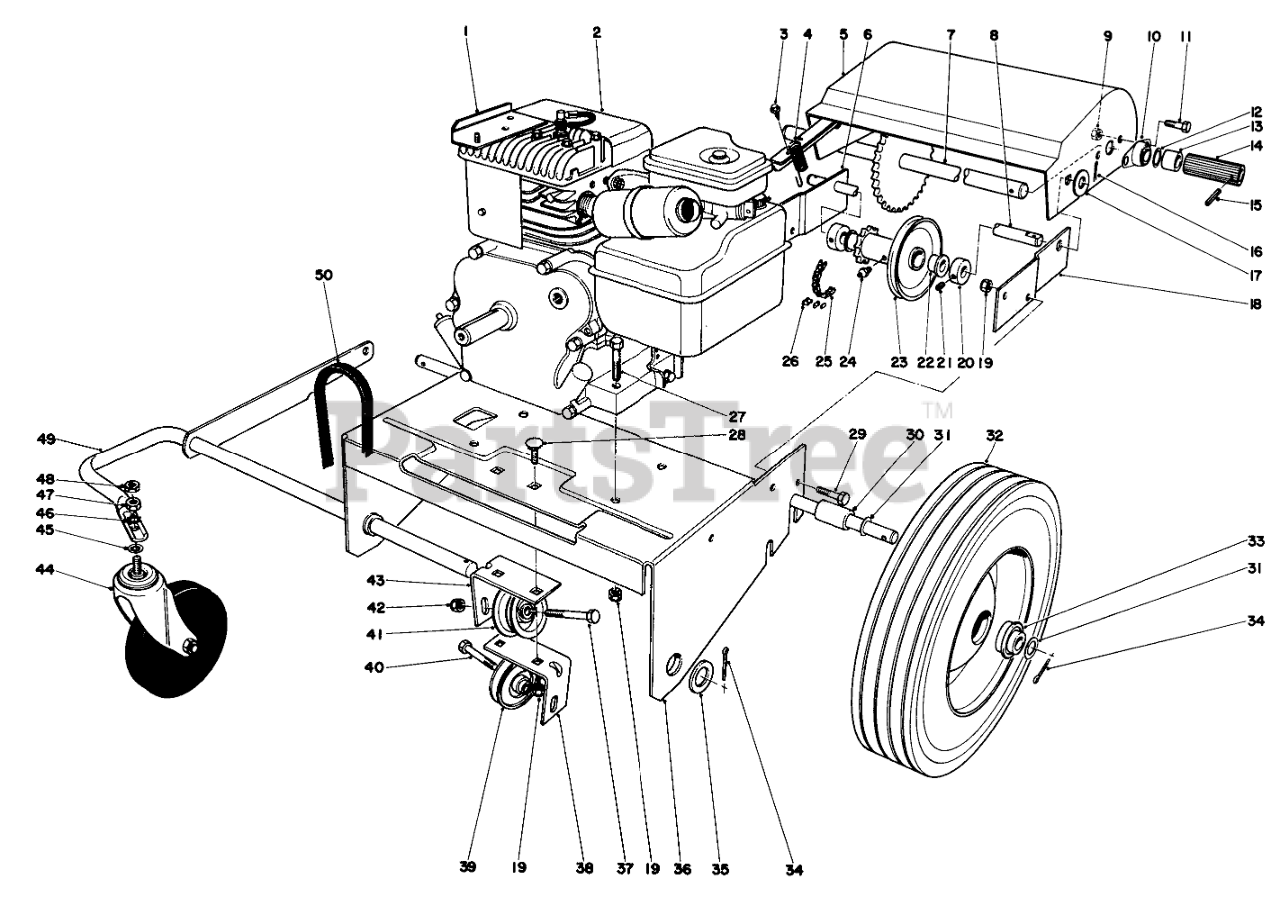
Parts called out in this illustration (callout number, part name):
1	MOUNTING BRKT WA
2	Engine
3	SCREW-HH
4	SPRING-TRACTION
5	GUARD WA
6	Mounting Bracket
7	SHAFT-WHEEL, FRICTION
8	SHAFT-IDLER
9	NUT-LOCK, NI
10	BEARING-MOUNT, FLANGE
11	SCREW-HH
12	WASHER
13	SPACER
14	WHEEL-FRICTION
15	PIN-ROLL, SLOTTED
16	PIN-COTTER
17	WASHER-FLAT
18	Mounting Bracket
19	NUT-LOCK, CONE
20	COLLAR
21	SCREW-SET, HSH
22	BUSHING-FLANGE
23	Idler (Incl. Ref. #22 & 24)
24	FITTING-GREASE
25	Chain Traction
26	LINK-CONNECTING, NO. 35
27	SCREW-HH
28	SCREW-CARR
29	SCREW-HH
30	SPACER-AXLE
31	WASHER
32	Wheel (Incl. Ref. #33)
33	BEARING
34	PIN-COTTER
35	WASHER-FLAT
36	Engine Plate
37	SCREW-HH
38	Bracket-Idler Mount L.H.
39	PULLEY-IDLER
40	SCREW-HH
41	PULLEY-IDLER
42	NUT-LOCK, CONE
43	Bracket-Idler Mount R.H.
44	CASTER
45	WASHER-LOCK/INT
46	WASHER-LOCK, EXT
47	NUT-HH
48	1/2-13 CONELOCK NUT
49	Front Wheel Support
50	BELT-V
